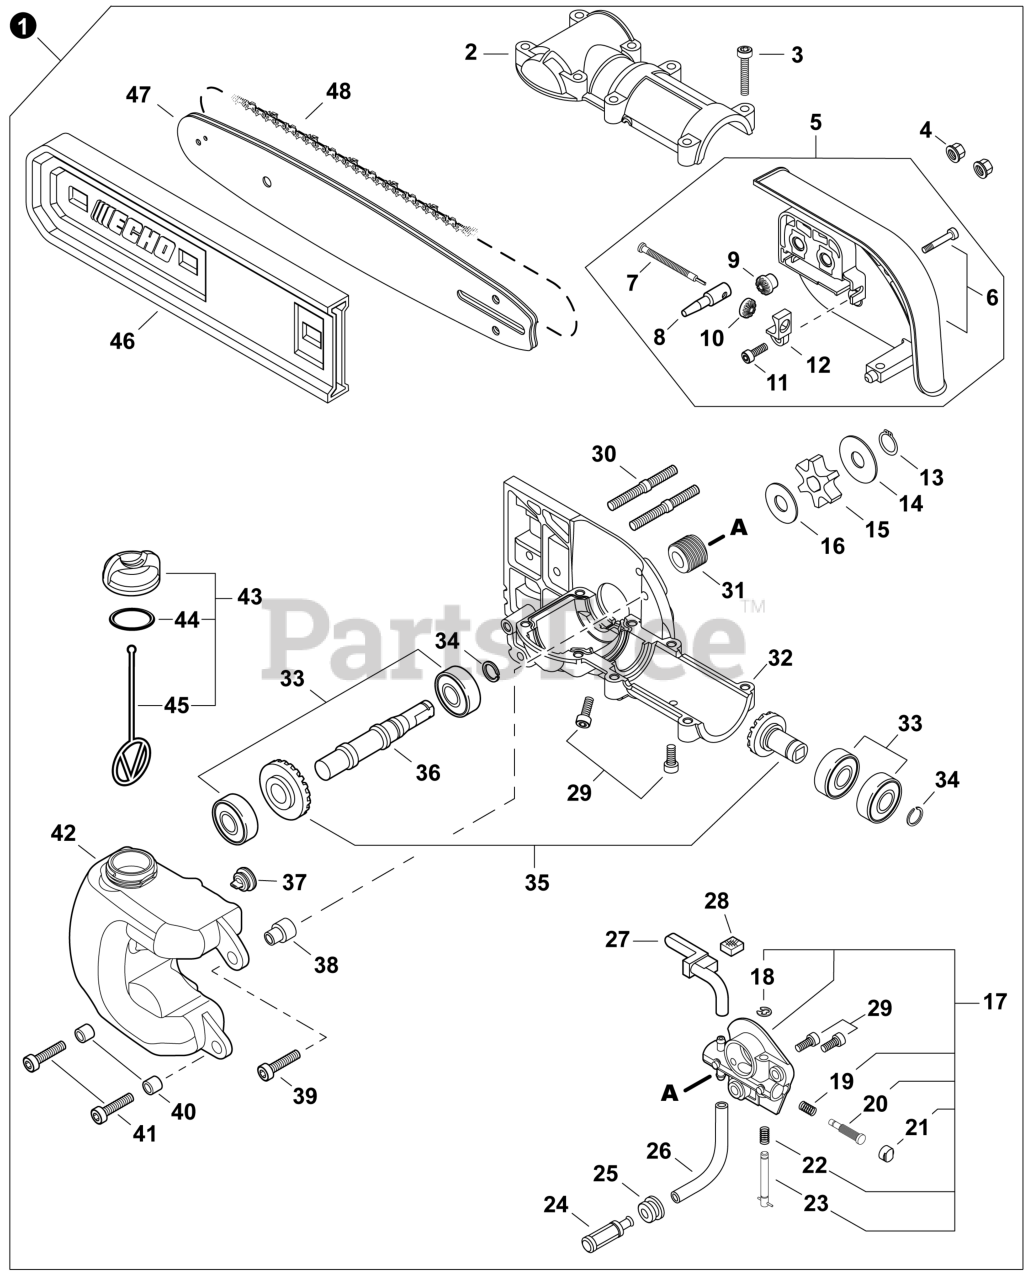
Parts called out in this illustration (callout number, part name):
1	CUTTING HEAD KIT
2	COVER, GEAR CASE
3	BOLT, TORX 5x25
4	NUT, FLANGE M6
5	SPROCKET GUARD ASSY
6	GUARD, SPROCKET
8	TENSIONER, CHAIN
9	GEAR - 14 TOOTH
10	GEAR - 14 TOOTH
11	SCREW 4
12	COLLAR 8
13	RING, SNAP
14	WASHER 10
15	SPROCKET, DRIVE
16	WASHER 10
17	AUTO-OILER ASSY
20	PLUNGER ASSY
21	CAP, PLUNGER
23	ADJUSTER, OILER
24	FILTER, OIL
26	PIPE 3x6x70
27	PIPE, OIL OUTLET
28	PAD, FOAM
29	BOLT, TORX 5x10
30	BOLT, STUD 6
31	GEAR, WORM
32	CASE, GEAR
33	BEARING, BALL
34	RING, SNAP 12
35	GEAR SET
36	SHAFT, GEAR
37	VENT ASSY
38	COLLAR 6
39	BOLT, TORX 5x25
40	SPACER 6.2x7.8x6
41	BOLT, TORX 5x20
42	TANK, OIL
43	CAP ASSY
44	O-RING 18
45	CONNECTOR, CAP L= 60 MM
46	SCABBARD 10"
47	GUIDE BAR, 10" 0.050" GA
48	SAW CHAIN 10" 0.050" GA
